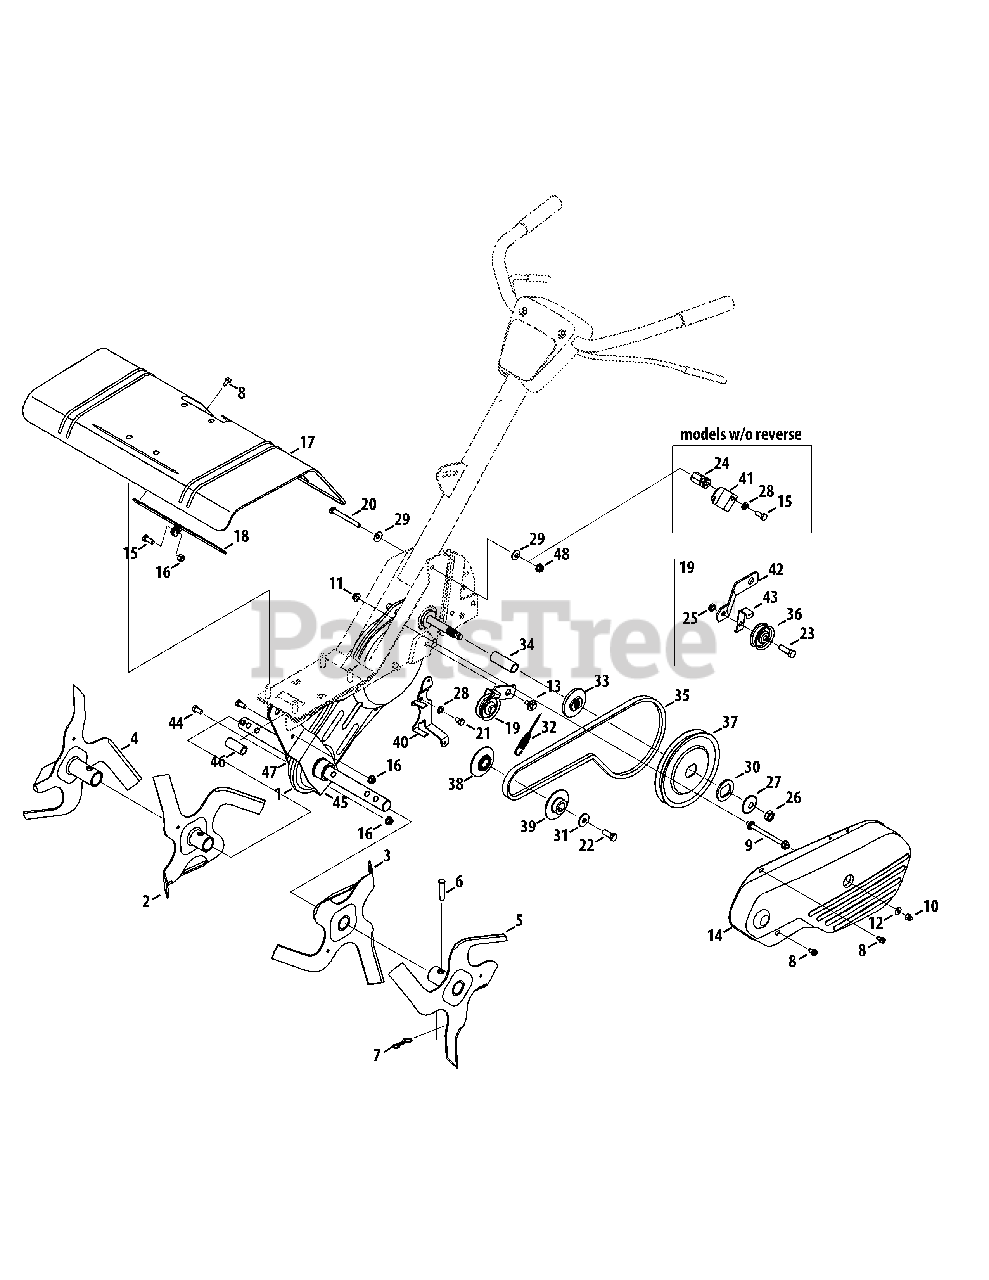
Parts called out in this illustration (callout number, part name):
1	Chain Case Assembly
2	Inner Tine Assembly, RH
3	Inner Tine Assembly, LH
4	Outer Tine Assembly, RH
5	Outer Tine Assembly, LH
6	Clevis Pin, .375 x 1.75
7	Bow Tie Cotter Pin
8	Screw, 1/4-20 x 0.500
9	Bolt, Belt Cover
10	Cap Lock Nut, 1/4-20
11	Nut, 5/16-18, Flange Lock
12	Flat Washer, .271 x .630 x .065
13	Shoulder Screw, .560 x .165 5/16-18
15	Hex Head Screw, 5/16-18 x .75
16	Nut, 5/16-18, Flange Lock
18	Bracket, Tine Shield
19	Idler Bracket Assembly
20	Hex Head Screw, 5/16-18 x 3.00
21	Hex Head Screw, 5/16-24 x .625
22	Hex Head Screw, 3/8-24 x 1.00
23	Hex Head Screw, 3/8-16 x 1.25
24	Hex Nut, 5/16-18*
25	Jamlock Nut, 3/8-16
26	Nut, 1/2-20, Jam
27	Washer, .531 x 1.62 x .045
28	Lock Washer, 5/16
29	Bell Washer, .340 x .872 x .060
30	Flat Washer, 1.26 x 1.87 x .150
31	Bell Washer, .396 x 1.140 x .095
32	Forward Clutch Cable
33	Pulley Adaptor
34	Spacer, .64 ID x 2.4
35	Belt, 4L x 41.9 LG
36	Pulley 1.88 OD
37	Pulley 6.00 OD
38	Inner Engine Pulley
39	Outer Engine Pulley
40	Belt Keeper Bracket
41	Cable Guide Bracket
42	Idler Bracket
43	Belt Keeper
44	Hex Head Screw, 5/16-18 x .625
46	Spacer, .505 ID x .75 OD x 1.75
48	Flange Nut 5/16-18 (w/ reverse)
